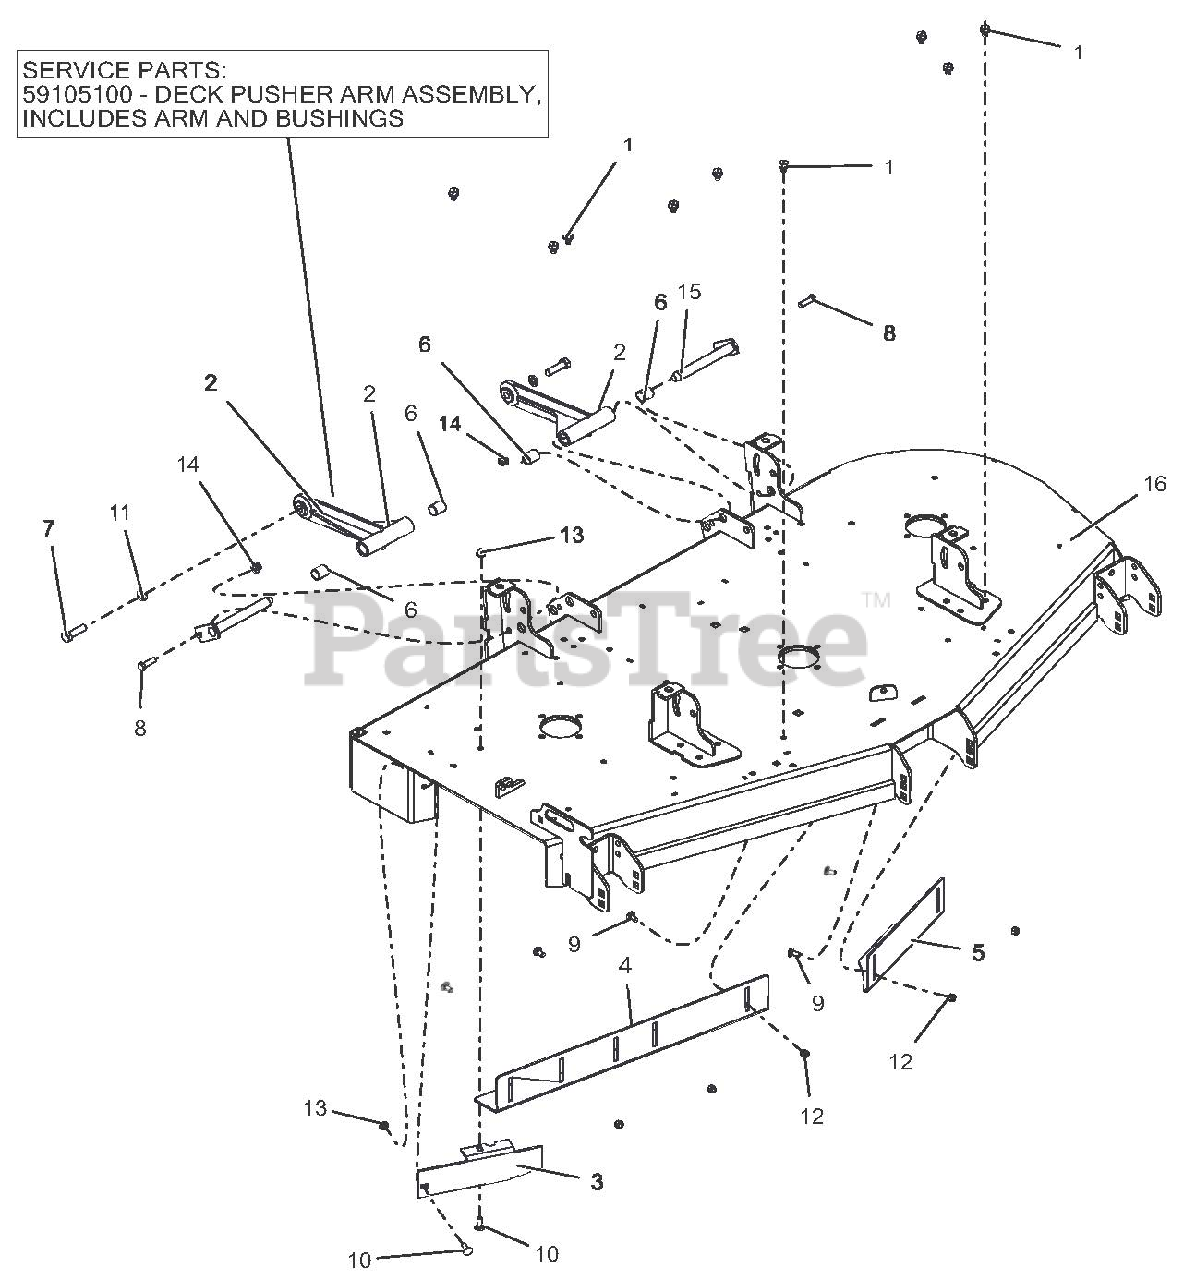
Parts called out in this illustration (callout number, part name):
1	SCR-TAP .38-16X.50 HWH TR YWZ
2	WLDMT, DECK PUSHER ARM
2	DECK PUSHER ARM ASSEMBLY
3	BAFFLE, 60" DISCHARGE
4	BAFFLE, 60" RH VACUUM
5	BAFFLE, 60" LH VACUUM
6	BRG, .750 X .875 X 1.000
7	BLT-HEX .50-13X1.75 GR5 YWZC EP80
8	BLT-HEX .38-16X1.25 GR5 YWZC
9	BLT-RDHDSQNK .31-18X.75 G5 YWZC
10	BLT-RDHDSQSHNK .31-18X1.00 G5 Y
11	WSHR-LK .50X.125 REG YWZC
12	NUT-LK-NYL .312-18 YWZC
13	NUT-LK-NYL-FLG .31-18 YWZC
14	NUT-LK-NYL-FLG .38-16 YWZC
15	WLDMT, MOWER MTG. PIN
16	KIT, PT160 MOWER DECK W/SAFETY DECALS-RED
